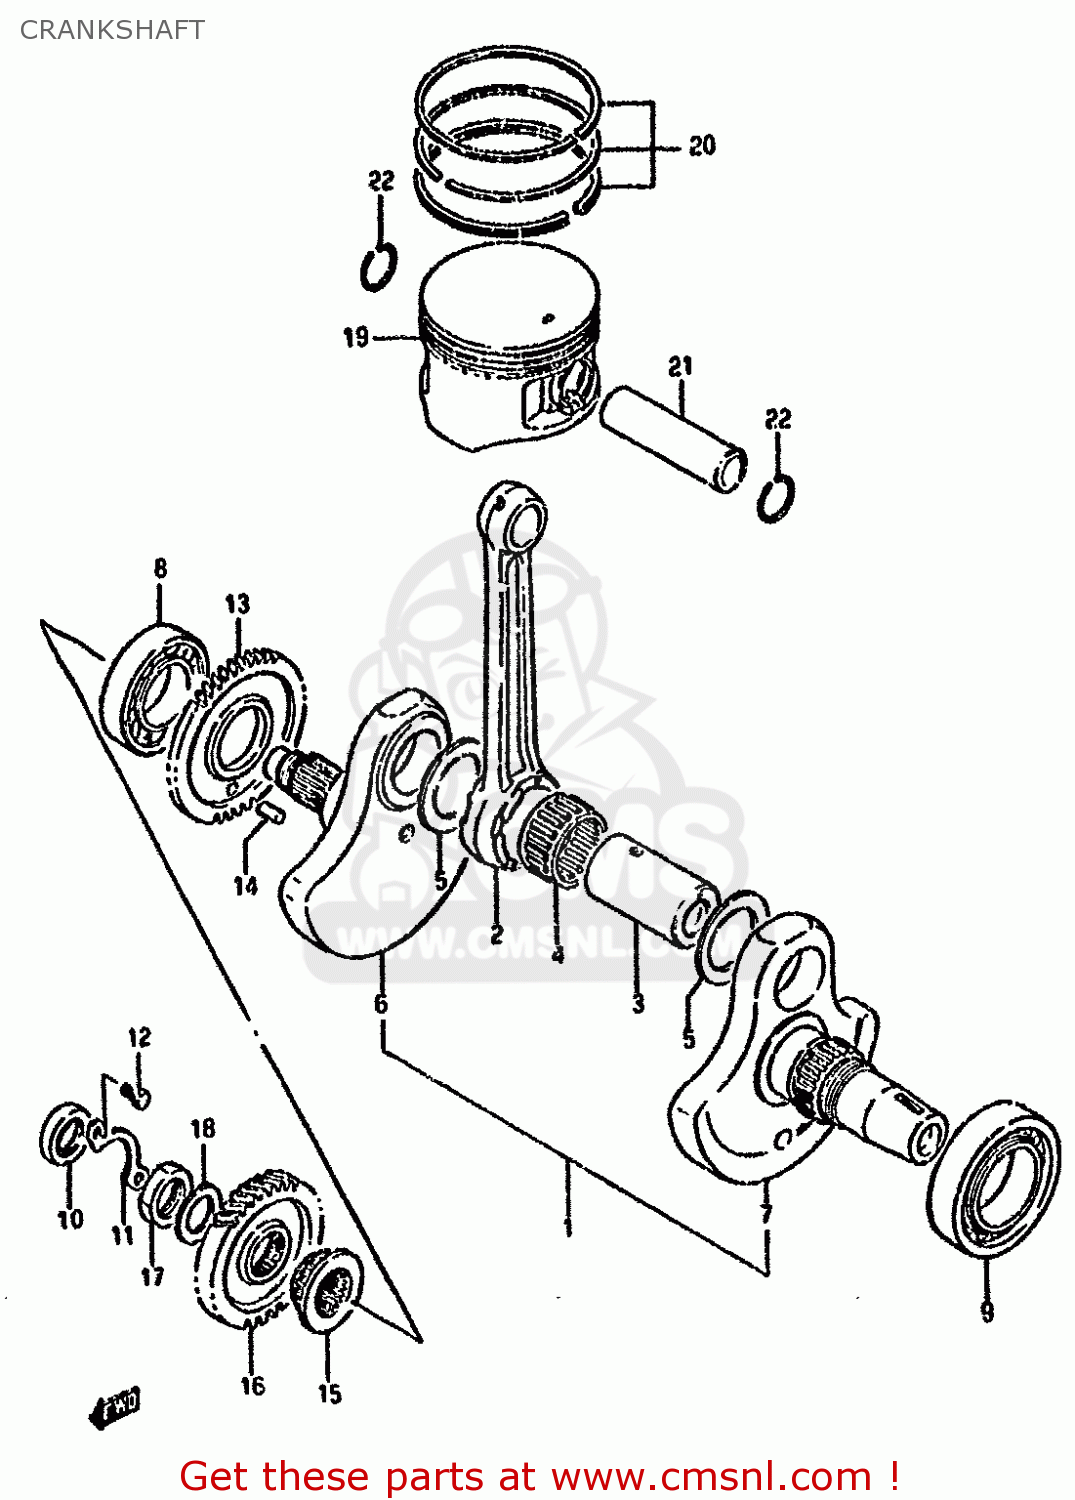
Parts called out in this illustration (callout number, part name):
1	CRANKSHAFT ASSY
2	ROD,CONNECTING
3	PIN,CRANK
4	BEARING(37X47X25)
5	WASHER(37X55X1)
6	CRANKSHAFT,R
7	CRANKSHAFT,L
8	BEARING(35X72X17)
9	BEARING(40X80X18)
10	SEAL,OIL(16X30X6)
11	RETAINER,CRANKSHAFT OIL SEAL,R
12	BOLT
13	GEAR,CRANK BALANCER DRIVE
14	PIN
15	SPROCKET,CAM CHAIN DRIVE
16	GEAR,PRIMARY DRIVE
17	NUT (20MM)
18	WASHER
19	PISTON
20	RING SET,PISTON
21	PIN,PISTON
22	CIRCLIP
